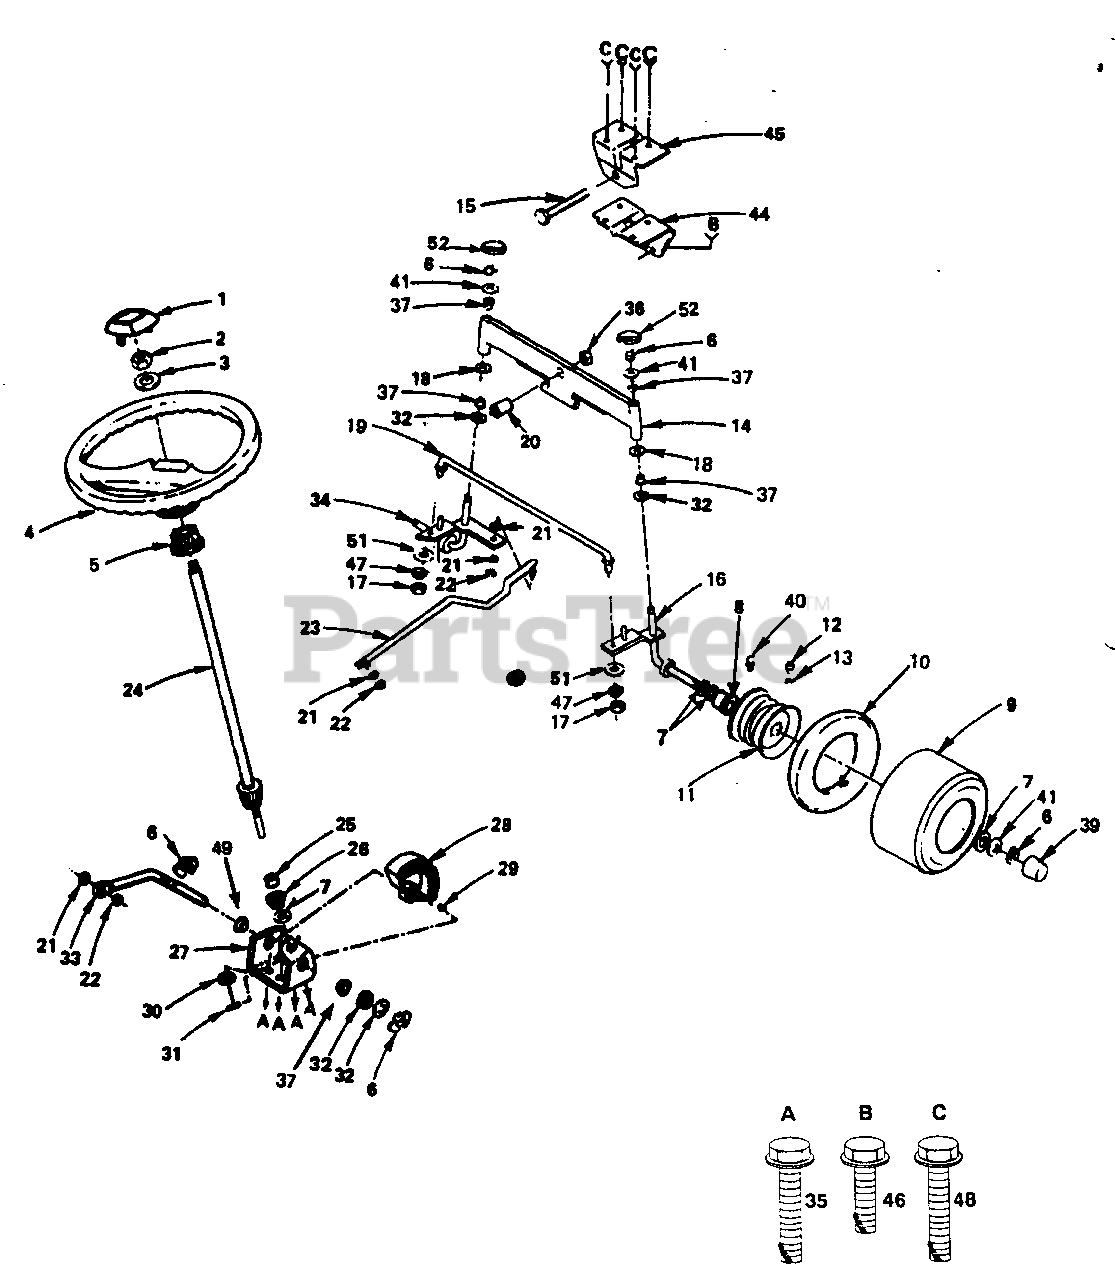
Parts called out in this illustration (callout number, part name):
1	Insert, Steering Wheel (AYP part number)
2	Nut, Hex, Toplock Jam 1/2-20 (AYP part number)
3	Washer 17/32 x 2-1/4 x .160 (AYP part number)
4	Steering Wheel (AYP part number)
5	Adapter, Steering Wheel (AYP part number)
6	Ring, Klip (AYP part number)
7	Washer 25/32 x 1-1/4 x 16 Gauge (AYP part number)
8	Wheel Bearings, Front (AYP part number)
9	Tire (AYP part number)
10	Tube, Tire
11	Rim Assembly, Front (AYP part number)
12	Stem, Valve (AYP part number)
13	Cap, Valve (AYP part number)
14	Axle Assembly, Front (AYP part number)
15	Bolt, Hex 5/8-11 x 3-3/4 (AYP part number)
16	Spindle, Assembly, R.H. (AYP part number)
17	Nut, Hex 5/16-24 (AYP part number)
18	Washer 27/32 x 1-1/4 x 16 Gauge (AYP part number)
19	Rod, Tie (AYP part number)
20	Spacer, Bearing (AYP part number)
21	Washer, Lock 3/8 (AYP part number)
22	Nut, Hex 3/8-24 (AYP part number)
23	Link, Drag (AYP part number)
24	Shaft Assembly, Steering (AYP part number)
25	Washer (AYP part number)
26	Support, Shaft (AYP part number)
27	Bracket, Steering (AYP part number)
28	Gear, Sector (AYP part number)
29	Screw, Socket, Hex 1/4-20 x 5/8 (AYP part number)
30	Washer, Shim 1/4 x 5/8 x .062 (AYP part number)
31	Washer, Lock 1/4 (AYP part number)
32	Bearing, Thrust (AYP part number)
33	Shaft, Pitman (AYP part number)
34	Spindle Assembly, L.H. (AYP part number)
35	Screw, Hex Washer Head, Thread Forming 3/8 -16 x 3/4 Type TT (AYP part number)
36	Locknut, Flange 5/8-16 (AYP part number)
37	Bearing (AYP part number)
39	Cap, Axle (AYP part number)
40	Fitting, Grease (AYP part number)
41	Washer 25/32 x 1-5/8 x 16 Gauge (AYP part number)
44	Support, Saddle, Front (AYP part number)
45	Support, Saddle, Rear (AYP part number)
46	Screw, Hex Washer Threaded, Rolling 5/16-18), (AYP part number)
47	Washer, Lock 5/16 (AYP part number)
48	Screw, Special (AYP part number)
49	Nyliner, Snap In (AYP part number)
51	Washer 11/32 x 3/4 x 16 Gauge (AYP part number)
52	Cap, Spindle (AYP part number)
